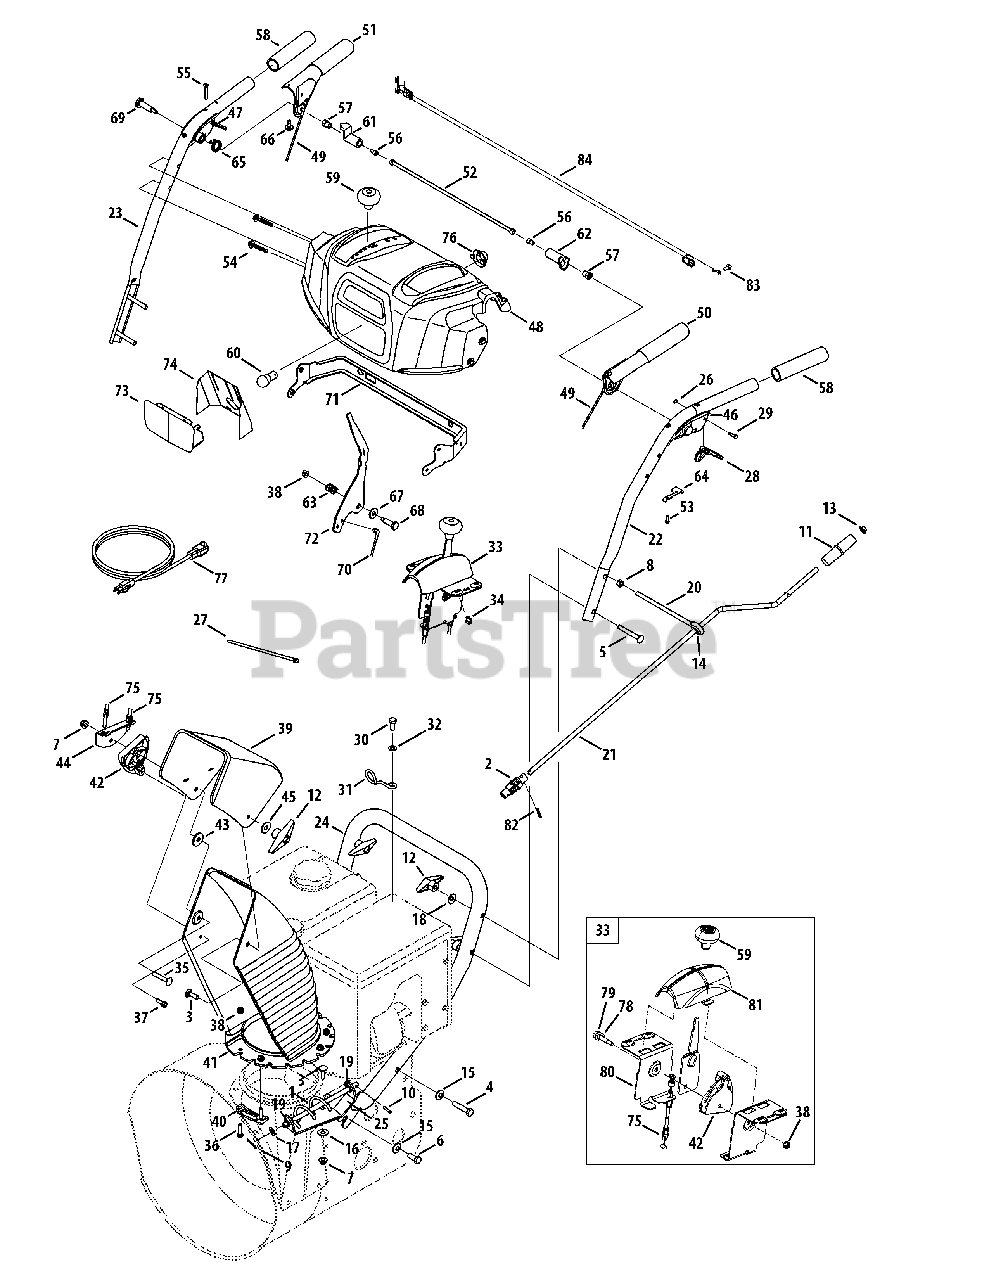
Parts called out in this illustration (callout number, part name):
1	Chute Crank Assembly
2	Joint Block Assembly
3	Screw, Carriage, 5/16-18 x 1.0
4	Screw, Hex, 3/8-16 x 2.00 Lock
5	Screw, Carriage, 5/16-18 x 2.5
6	Screw, Hex, 3/8-16 x 1.0 Lock, Gr5
7	Flange Lock Nut, 5/16-18
8	Hex Nut, 5/16-18
9	Internal Cotter Pin
10	Spring Pin
11	Knob, Crank
12	Wing Knob
13	Cap, Push, 3/8
14	Grommet, Rubber
15	Washer, Bel, .375 x .87 x .063
16	Washer, Flat, .349 x .879 .063
17	Washer, .375 x .738 x .063
18	Washer, Belleville, .34 x .872 x .06
19	Plastic Bushing, .380 I.D.
22	Handle, Upper - LH
23	Handle, Upper - RH
26	Ring, Retainer
27	Cable Tie
30	Hex Head Screw, MB 1.25
31	Cable Guide
32	Flat Washer, .330 x .630 x .0635
33	2-Way Chute Control™ Assy
34	Hi-Lo Screw, 1/4-15 x 0.5
35	Bolt, Carriage, 5/16-18 x 1.75
36	Screw, 1/4-20 x 1.00
37	Hi-Lo Screw, 1/4-15 x .75
38	Flange Lock Nut, 1/4-20
39	Upper Chute
40	Chute, Flange Keeper
41	Lower Chute
42	Chute Tilt Cable Guide
43	Flat Washer
45	Washer, Flat, .349 x .879
46	Handle Clutch Lock - LH
47	Handle Clutch Lock - RH
48	Handle Panel
49	Cable Assembly, Auger/Drive
50	Handle Engage Assy - LH
51	Handle Engage Assy - RH
52	Rod Ass’y, Clutch Lock Pivot
53	Screw, #8-16 x 0.50
54	Screw, 1/4-20 x 1.625
55	Screw, #10-24 x 0.375
56	Screw, 1/4-20 x.375
57	Shoulder Nut, 1/4-20
58	Hand Grip
59	Shift Knob
62	Clutch Lock Cam
63	Compression Spring
64	Clutch Lock Spring
65	Torsion Spring
66	Rubber Bumper
67	Flat Washer, .385 x .87 x .06
68	Shoulder Screw
69	Shoulder Screw, 1/4-20 x 1.345
70	Speed Selector Cable
71	Panel Bracket
73	Lens Panel
74	Reflector Label
75	Cable, Chute Tilt
76	Light Socket
77	Extension Cord, 110V
78	Washer, Spring, .39 x .625 x .012
79	Screw, Shoulder, .31 x .995:1/4-20
80	Bracket, Mounting
81	Cover, Tilt Cover
82	Internal Cotter Pin
83	Screw 1/4-20 x .50
84	Wire Harness
